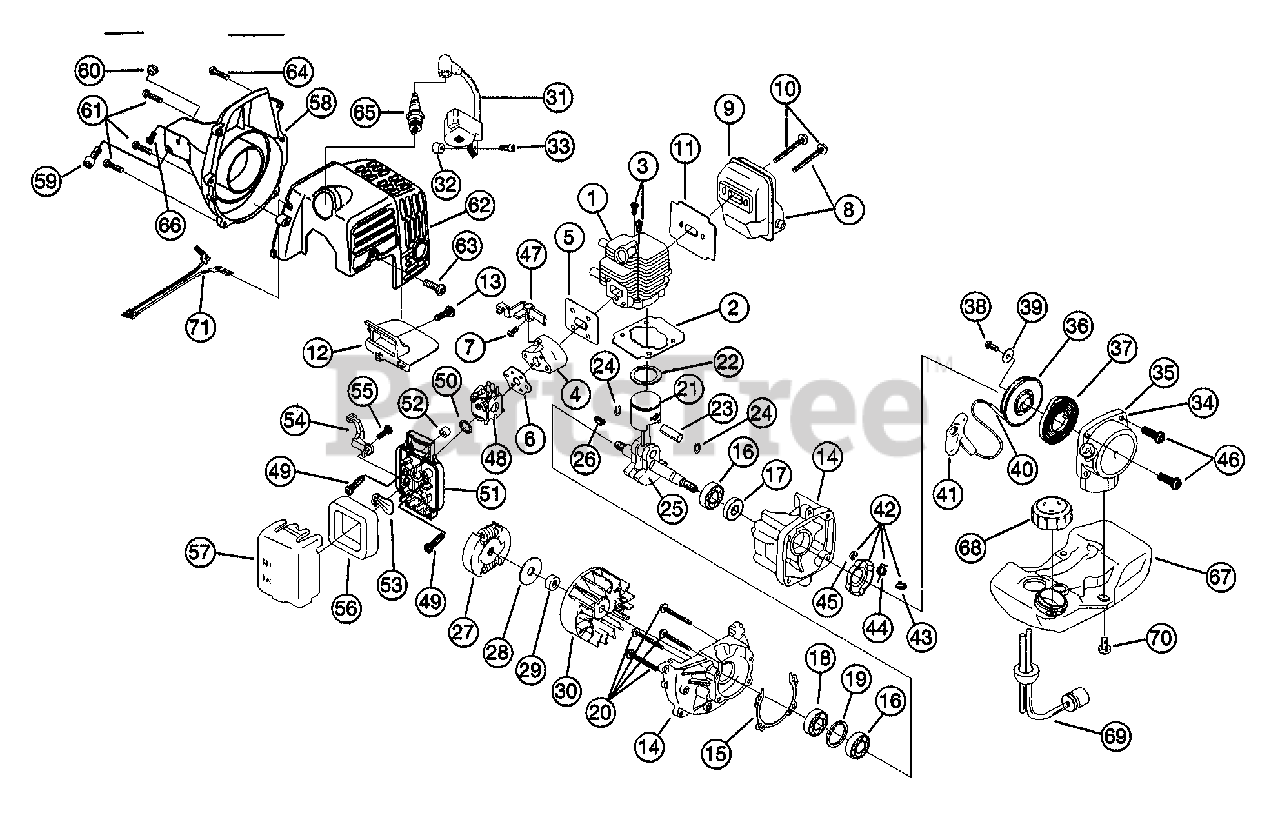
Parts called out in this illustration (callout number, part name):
2	Cylinder Base Gasket
5	Insulator Gasket
6	Carburetor Gasket
7	Screw and Washer
8	Muffler Assembly
11	Muffler Gasket
12	Muffler Plate
14	Crankcase Service Assembly
15	Crankcase Gasket
28	Clutch Washer
30	Flywheel Assembly
31	Module Assembly
34	Recoil Assembly
35	Recoil Case
36	Recoil Pulley
37	Recoil Spring
41	Pull Handle
42	Pulley Assembly
45	Retaining Ring
47	Throttle Bracket
48	Carburetor
51	Air Cleaner Assembly
53	Choke Plate
54	Choke Lever
57	Air Cleaner Cover
58	Clutch Housing Assembly
62	Engine Cover
67	Fuel Tank
68	Fuel Cap Assembly
69	Fuel Line Assembly
71	Lead Wire Assemby
